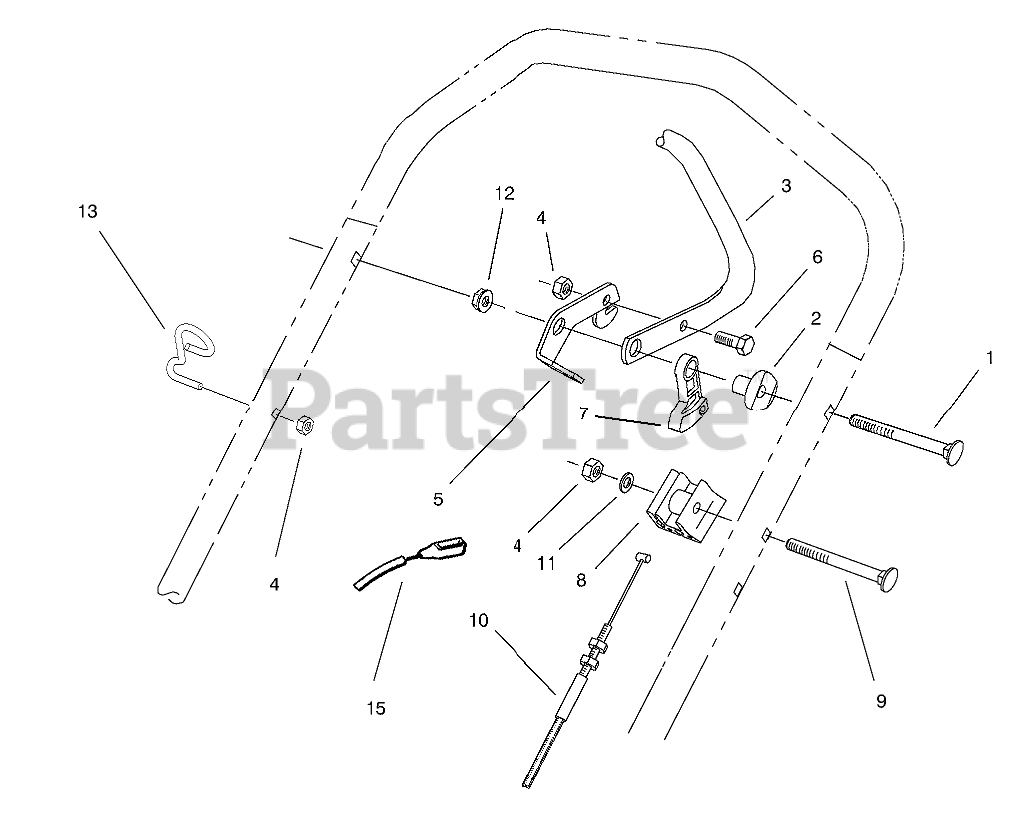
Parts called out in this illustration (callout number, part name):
1	SCREW-HANDLE
2	SPACER-SUPPORT
3	Bar-Control
4	NUT-LOCK, NI
5	LEVER-CONTROL
6	SCREW-HH
7	LEVER-TRACTION
8	SUPPORT-CABLE
9	SCREW-HANDLE
10	CABLE-TRACTION
11	WASHER-FLAT
12	NUT-LOCK, NI
13	GUIDE-ROPE
15	CABLE-BRAKE
